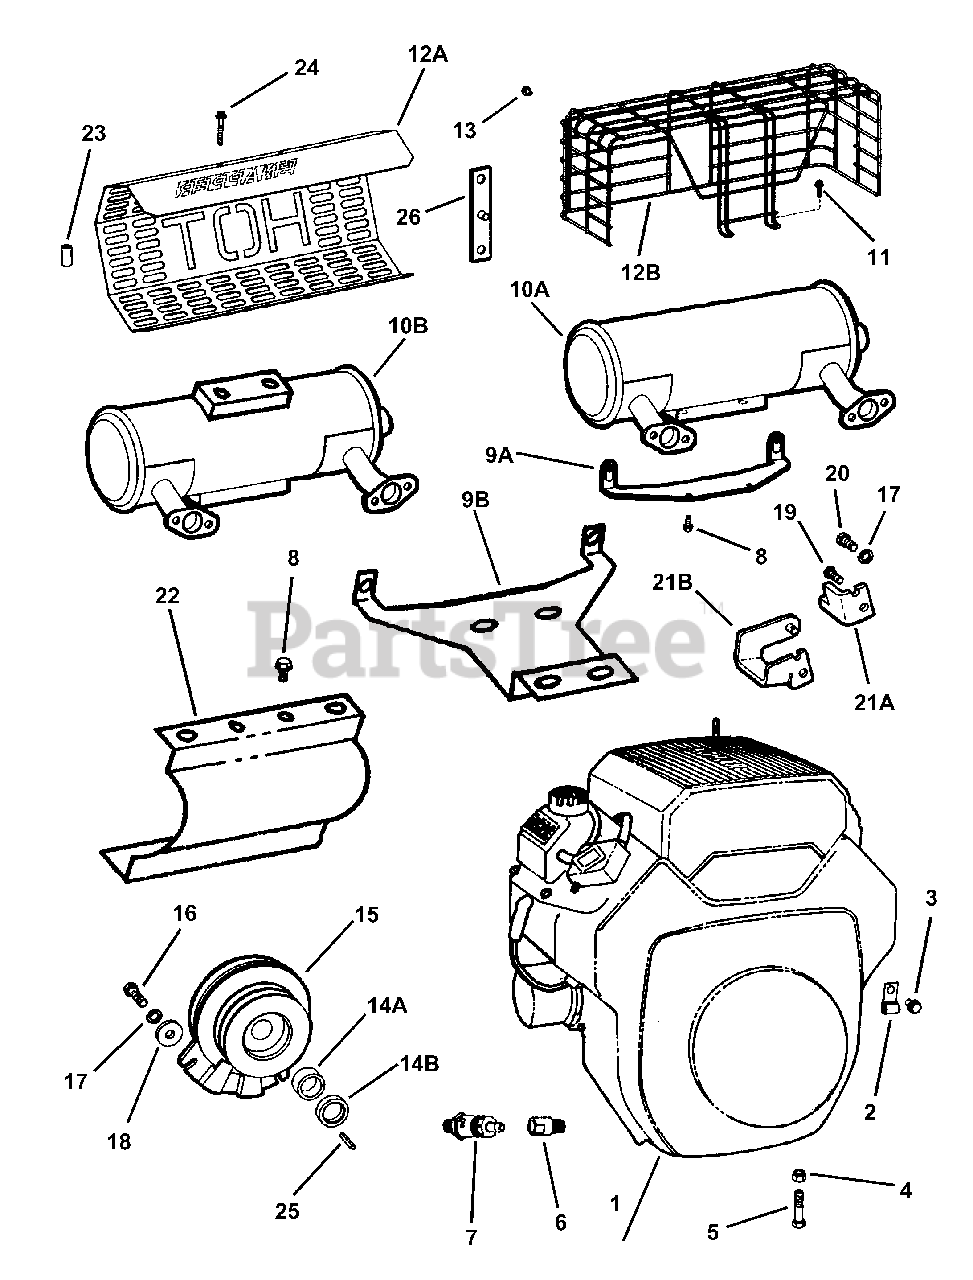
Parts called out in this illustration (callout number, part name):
2	J-CLIP, 3/8" Cushioned
3	SCREW, 5/16-18 x 5/8" Hex Washer Self Tap
4	NUT, 3/8-16 HEX NYLON LOCK
5	SCREW, 3/8-16 x 1-3/4" Hex Head Cap, Grade 5
6	OIL DRAIN, Short
7	ASSEMBLY, Oil Valve
8	SCREW, M6 x 1 x 6mm Hex Flange Cap
9A	BRACKET, Muffler, 22HP Kohler (Kohler P/N 24 126 10)
9B	BRACKET, Muffler, 25HP Kohler (Series 0)(Kohler P/N 24 126 48)
10B	MUFFLER, 25HP Kohler (Kohler P/N A-24 068 17)
12A	GUARD, Muffler (Kohler P/N 24 13 02-1)
12B	GUARD, Muffler
14A	SPACER, Clutch
14B	SPACER, Clutch (Model MZM2200KH Only)
15	CLUTCH, Electric
15	CLUTCH, Electric (Model MZM2200KH Only)
16	SCREW, 7/16-20 x 1-1/2" Hex Head Cap. Grade 5
17	WASHER, 7/16" Split Lock
18	WASHER, 7/16 I.D. x 1-3/8 O.D. x 1/4 Flat
19	BOLT, 3/8-16 X 1" GD5 CZ
20	PIN, COTTER, 1/8 X 1-1/4
21A	BRACKET, Anti-Rotation (5/16")
21B	BRACKET, Anti-Rotation (Model MZM2200KH Only)
22	SHIELD, Heat, 25HP Kohler
23	SPACER, Muffler Guard
24	SCREW, 1/4-20 x 1-1/2" Hex Washer Self-Tap
25	KEY, 1/4 Square x 1"
26	BRACKET, Torque
